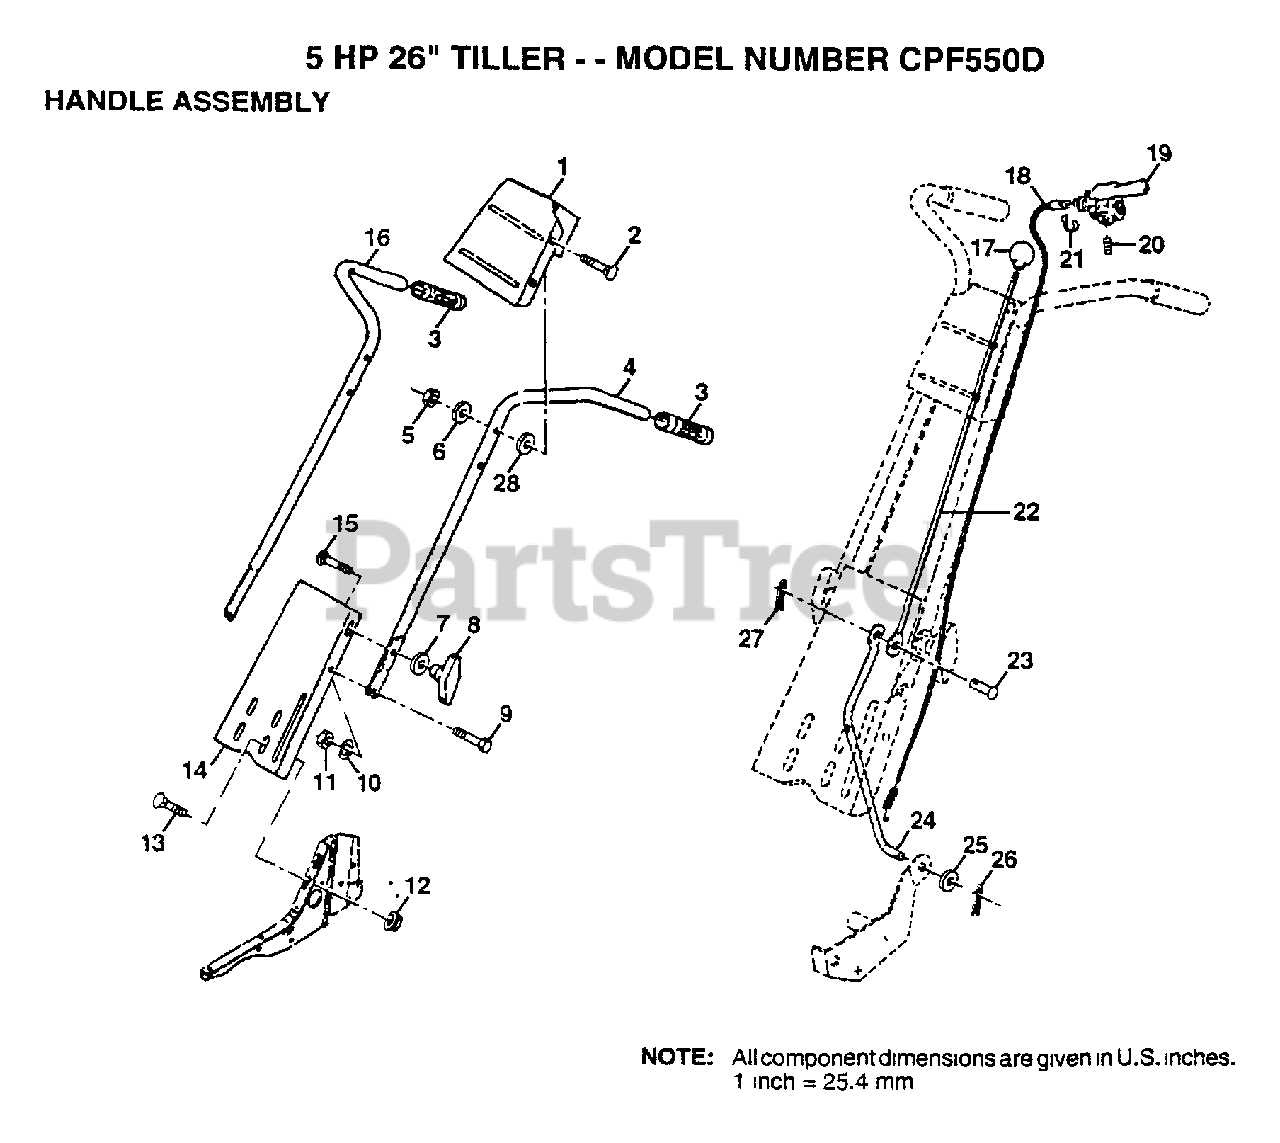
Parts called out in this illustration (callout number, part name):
1	"BRKT,HANDLE "
2	BOLT
3	GRIP NUB DOUBLE
6	WASHER
7	WASHER
8	KNOB HANDLE
10	LOCKWASHER
11	NUT.HEX.5/16-18
12	NUT
13	BOLT
14	"PANEL,HANDLE"
15	BOLT CRT
17	KNOB T(3/8 HOLE)
18	CABLE CLUTCH T
19	CONTROL LEVER TI
20	SCREW
21	E-RING
22	ROD REVERSE TI
23	RIVET.RD.HD.DRILL
24	REVERSE ROD TI
25	WASHER
26	COTTER PIN
28	WASHER
